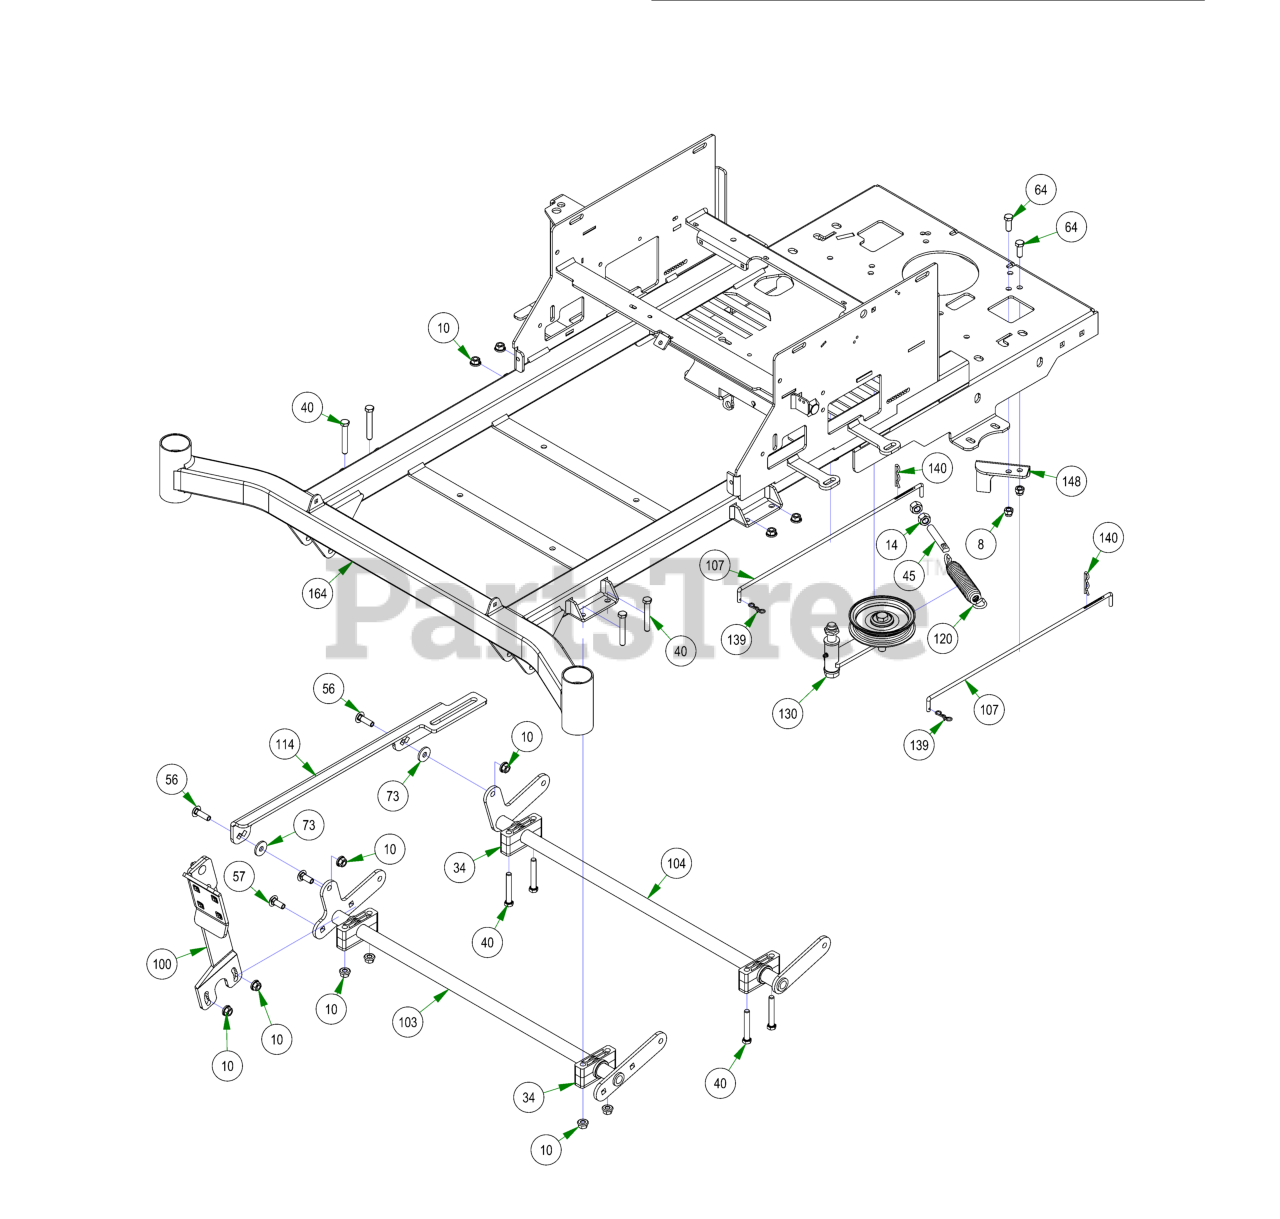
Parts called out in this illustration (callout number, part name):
8	3/8-16 NYLON INSERT LOCKNUT ZINC
10	3/8-16 NYLON INSERT FLANGE LOCKNUT (GR.F) ZINC
14	1/2-13 HEX NUT ZINC
34	Pillow Block Kit
40	3/8-16 X 2-1/2 HEX CAP SCREW (GR.5) ZINC
45	All Thread
56	3/8-16 X 1-1/4 CARRIAGE BOLT ZINC
57	3/8-16 X 1 CARRIAGE BOLT (GR.5) ZINC
64	3/8-16 X 1 GR 5 Hex Bolts Zinc
73	.390 ID X 1.12 OD X .125 THK FLAT WASHER NYLON
100	Foot Pedal Assembly
103	Actuator Bar Front- 2017 MZ/ZT
104	Actuator Bar Rear- 2017 MZ/ZT
107	Neutral Rod
114	2017 MZ/ZT Actuator Linkage
120	Deck Idler Spring
130	ZT Pump Idler
140	Neutral Rod Clip
148	2017 MZ Clutch Stop
164	2023 MZ-Avenger 54-60 Frame - Painted
